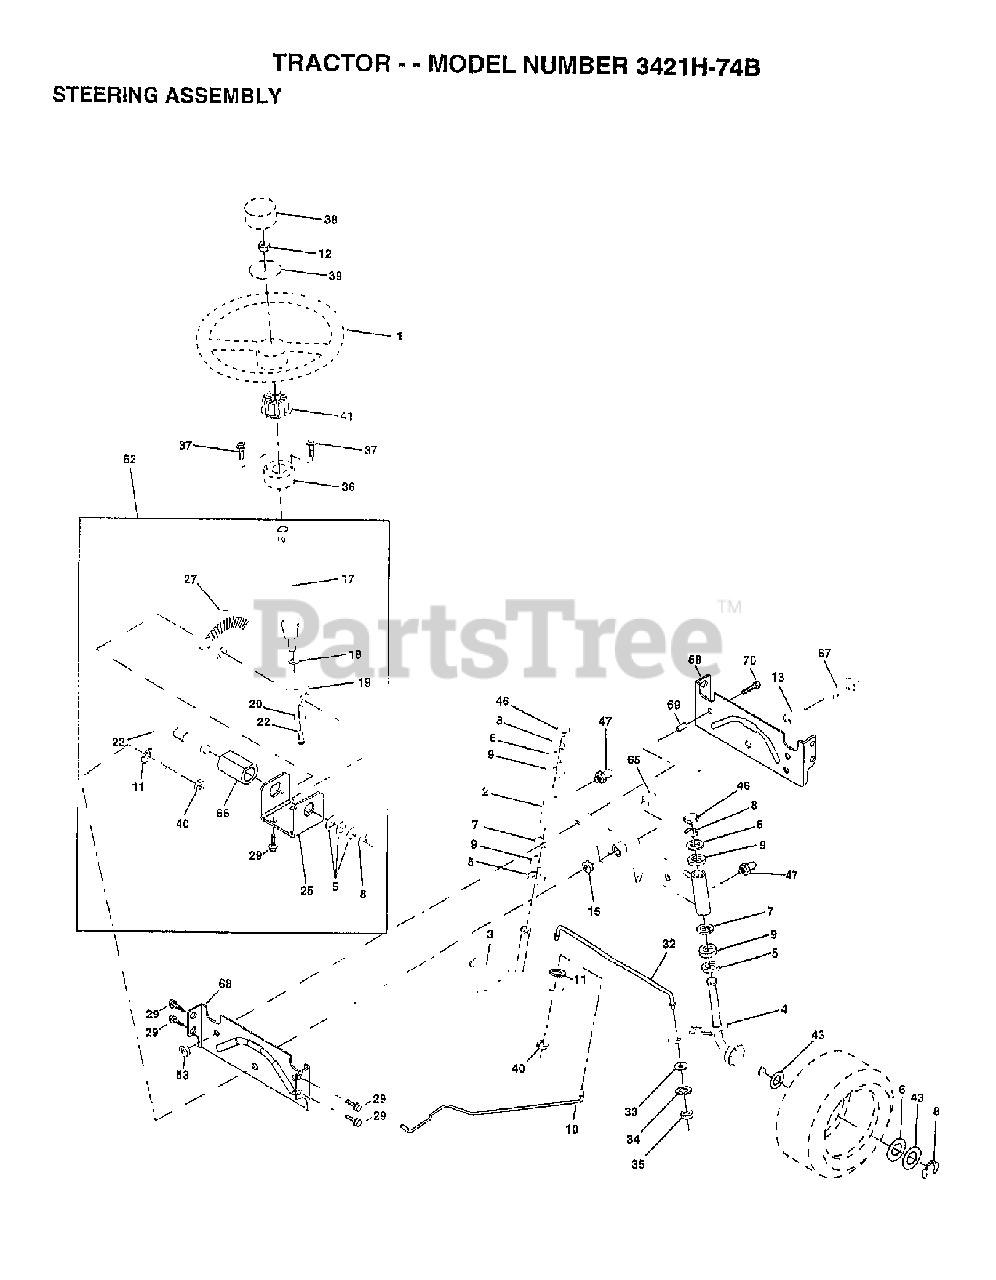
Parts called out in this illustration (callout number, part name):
1	Steering Wheel
2	Half Axle Assembly, Welded
3	SPINDLE.ASM.LH
5	WASHER THRUST
8	RING CLIP
9	BEARING.STEERING.COLUMN
10	DRAGLINK-STAMPED
11	WASHER, LOCK 3/8
12	NUT.HEX.1/2-20
13	BEARING AXLE
15	LOCK NUT
17	STEERING SHAFT
18	THRUST WASHER
19	SHAFT,SUPPORT
20	WASHER
23	SHAFT,PITMAN
25	BRACKET STEERING
27	GEAR.SECTOR
33	WASHER M
34	LOCKWASHER
35	LOCKNUT
37	SCREW.TT.#10-32X.5.3/8.FLANGE
38	INSERT STR WHL
40	NUT
46	CAP.SPINDLE.BLACK
47	ZERK.GREASE.TAPERED
51	NUT.71038.31-18.HEX.NYLOCK
53	LOCKNUT
54	BOLT.5/16-18X1-1/4 FULL.THREAD
62	STEERING KIT
65	SPACER AXLE
66	BEARING ARM
67	BOLT.HEX.FINISHED.5/8
68	AXLE, BRACE
69	SPACER BRACE AXLE
